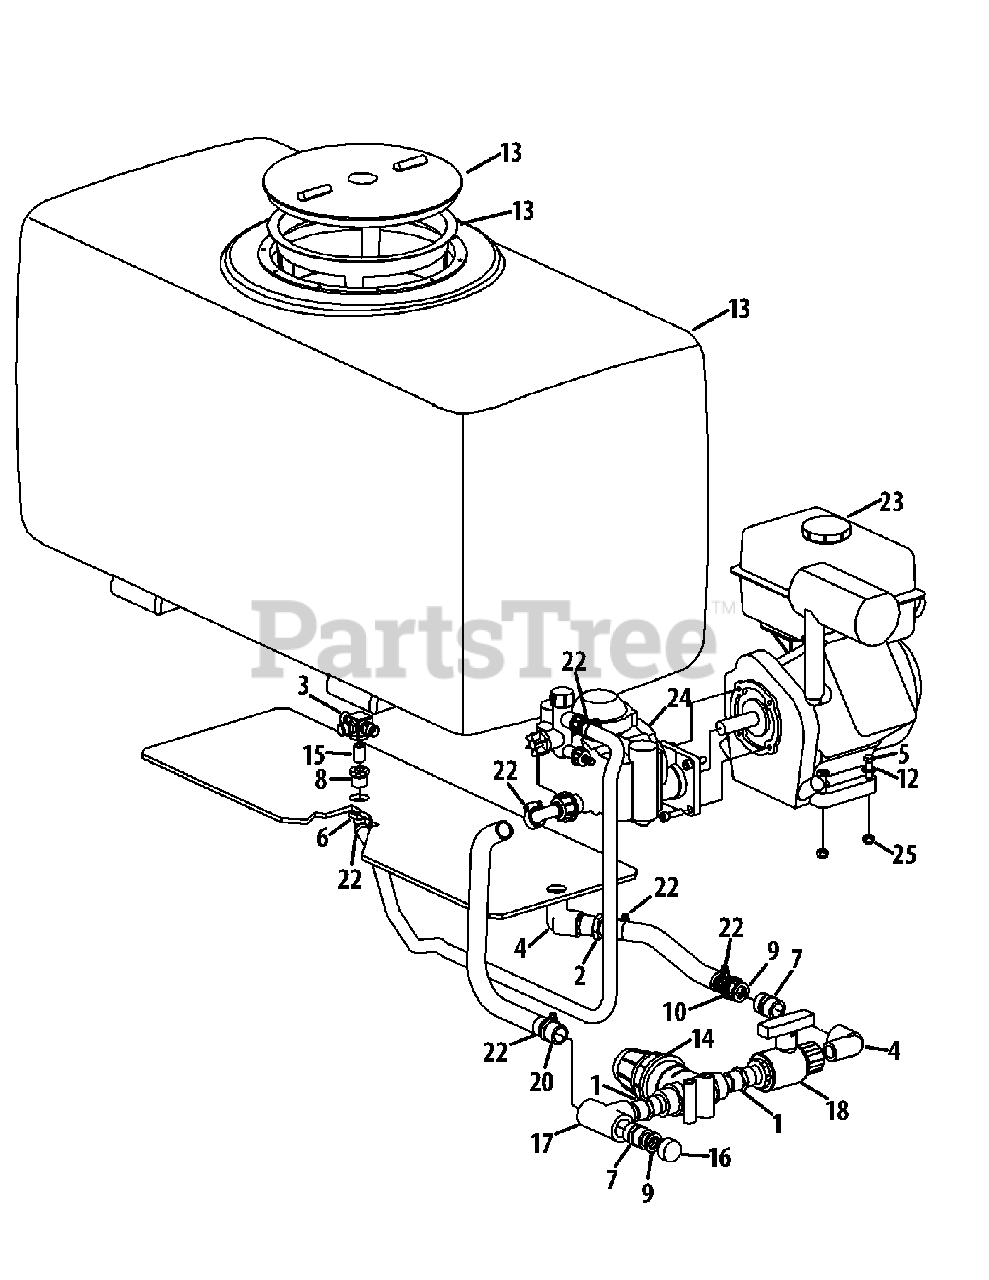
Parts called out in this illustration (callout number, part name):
1	Nipple, 3/4
2	Insulated Male Adapter, 3/4
3	Jet Agitator
4	Elbow, 3/4
5	Hex Screw, 5/16-18 x 1.75
6	90° Elbow, 1/2 x 1/2
7	Threaded Pipe Hose, 3/4 x 3/4
8	Reducer Bushing, 1/2 x 1/4
9	Hose Washer, 3/4
10	Brass Female Hose, 3/4
12	Washer, .344 x .688 x .063
13	50 Gallon Poly Tank
14	Strainer, 3/4
15	Brass Nipple, 1/4
16	Brass Hose Cap, 3/4
17	PVC Tee, 3/4
18	PVC Ball Valve, 3/4
20	Fitting, 3/4 x 5/8
22	Hose Clamp
23	Kawasaki Engine
24	Hypro Pump
25	Hex Lock Nut, 5/16-18
